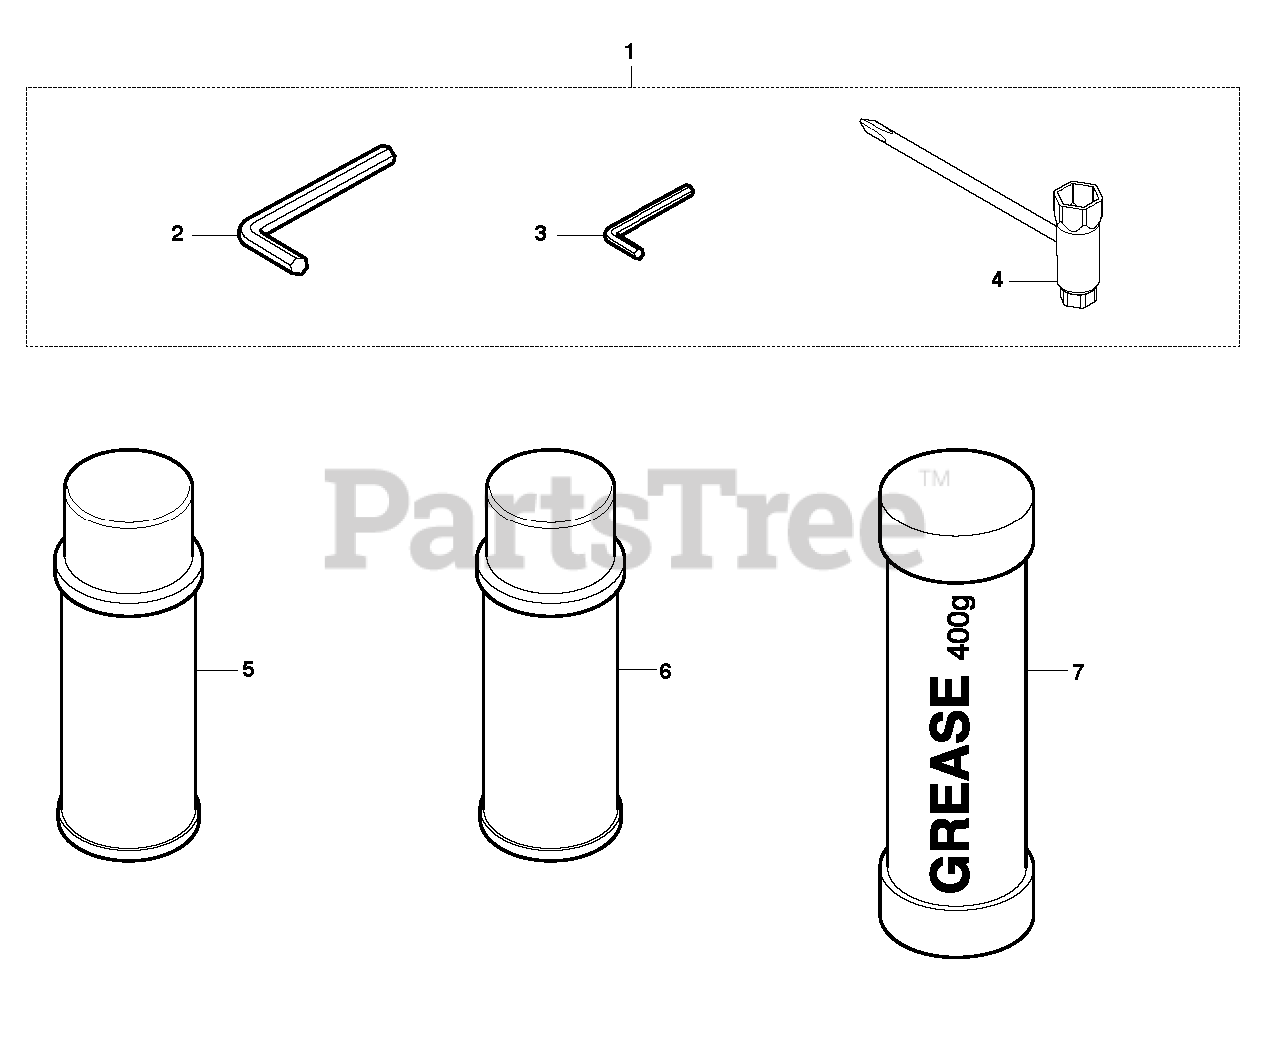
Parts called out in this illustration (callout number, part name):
1	ACCESSORY BAG
4	COMBINATION WRENCH
5	Ul 22 - 12 Pack
6	CUTTER BAR LUBE/12 PACK UL21
7	Grease 400 Grams
